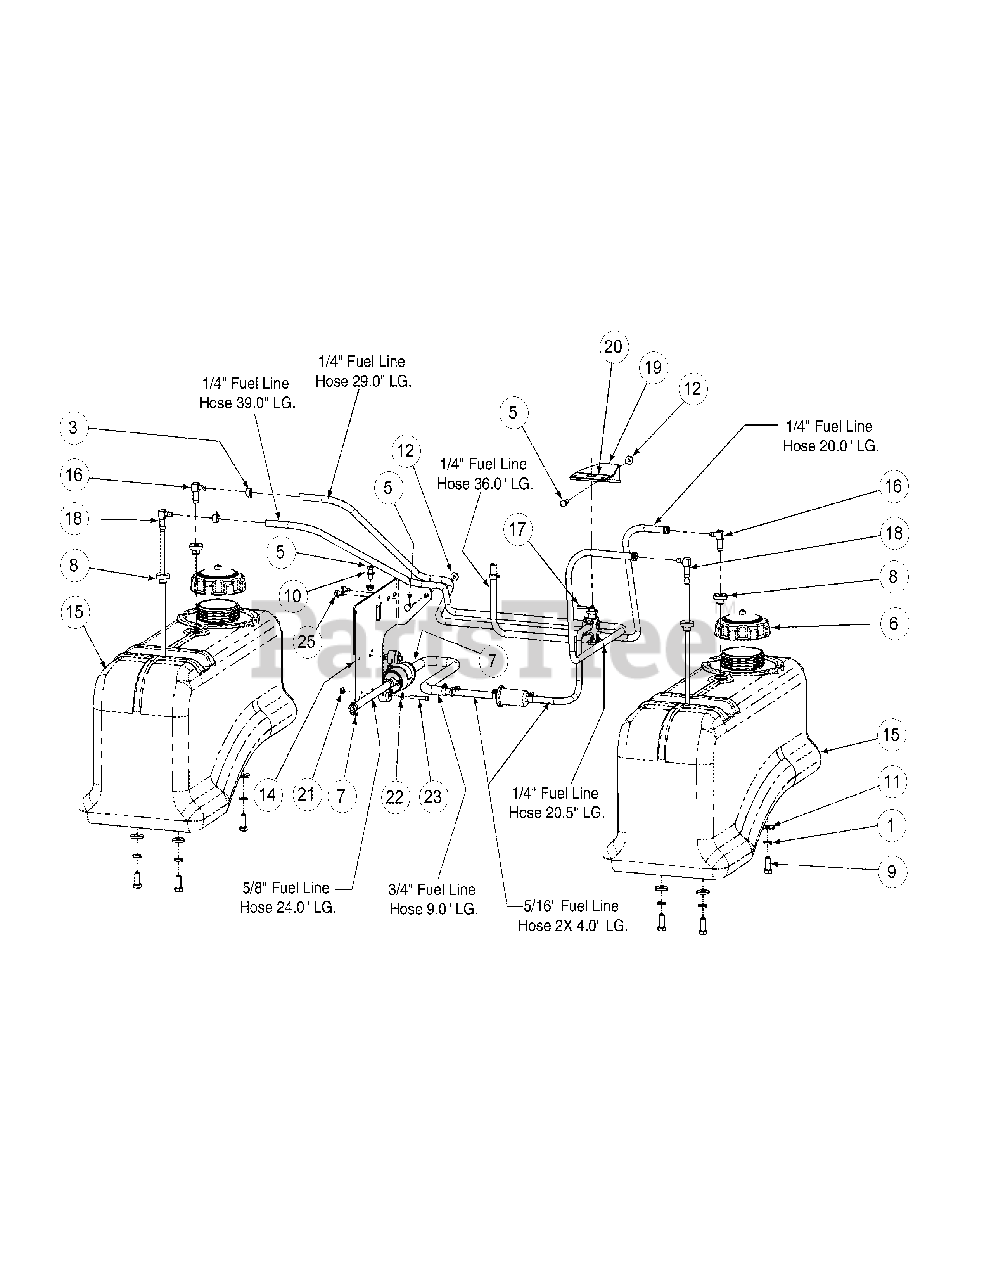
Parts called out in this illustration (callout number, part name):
1	Lock Washer, 3/8
2	Hose, 1/4" Fuel Line 144.5 inches
3	Clamp, Union
4	Cable Tie
5	Hex Cap Screw, 1/4-20 x 3/4
6	Fuel Cap, 3.5
7	Hose Clamp
8	Fuel Tank Grommet
9	Hex, Cap Screw, 3/8-16, .88
10	Washer, 5/16
11	Flat Washer, .406 ID, 1.0 OD, .105
12	Hex Flange Lock Nut, 1/4-20
13	Fuel Hose, .38 ID x .625 OD 24 inches
14	Pump Mounting Bracket
15	Fuel Tank
16	Fuel Fitting, Return
17	Shut Off Fuel Valve
18	Fuel Fitting, Pickup
19	Fuel Valve Mounting Bracket
20	Decal, Fuel Tank Shut Off
21	Nut, 10-24, Nylon Insert
22	Washer, 3/16
23	Socket Head Screw, 10-24 x 1.25
24	Fuel Hose, .50 ID x .75 OD 9 inches
25	Self Tapping Screw, 1/4-20 x .50
26	Hose, 5/16" Fuel Line 8 inches
